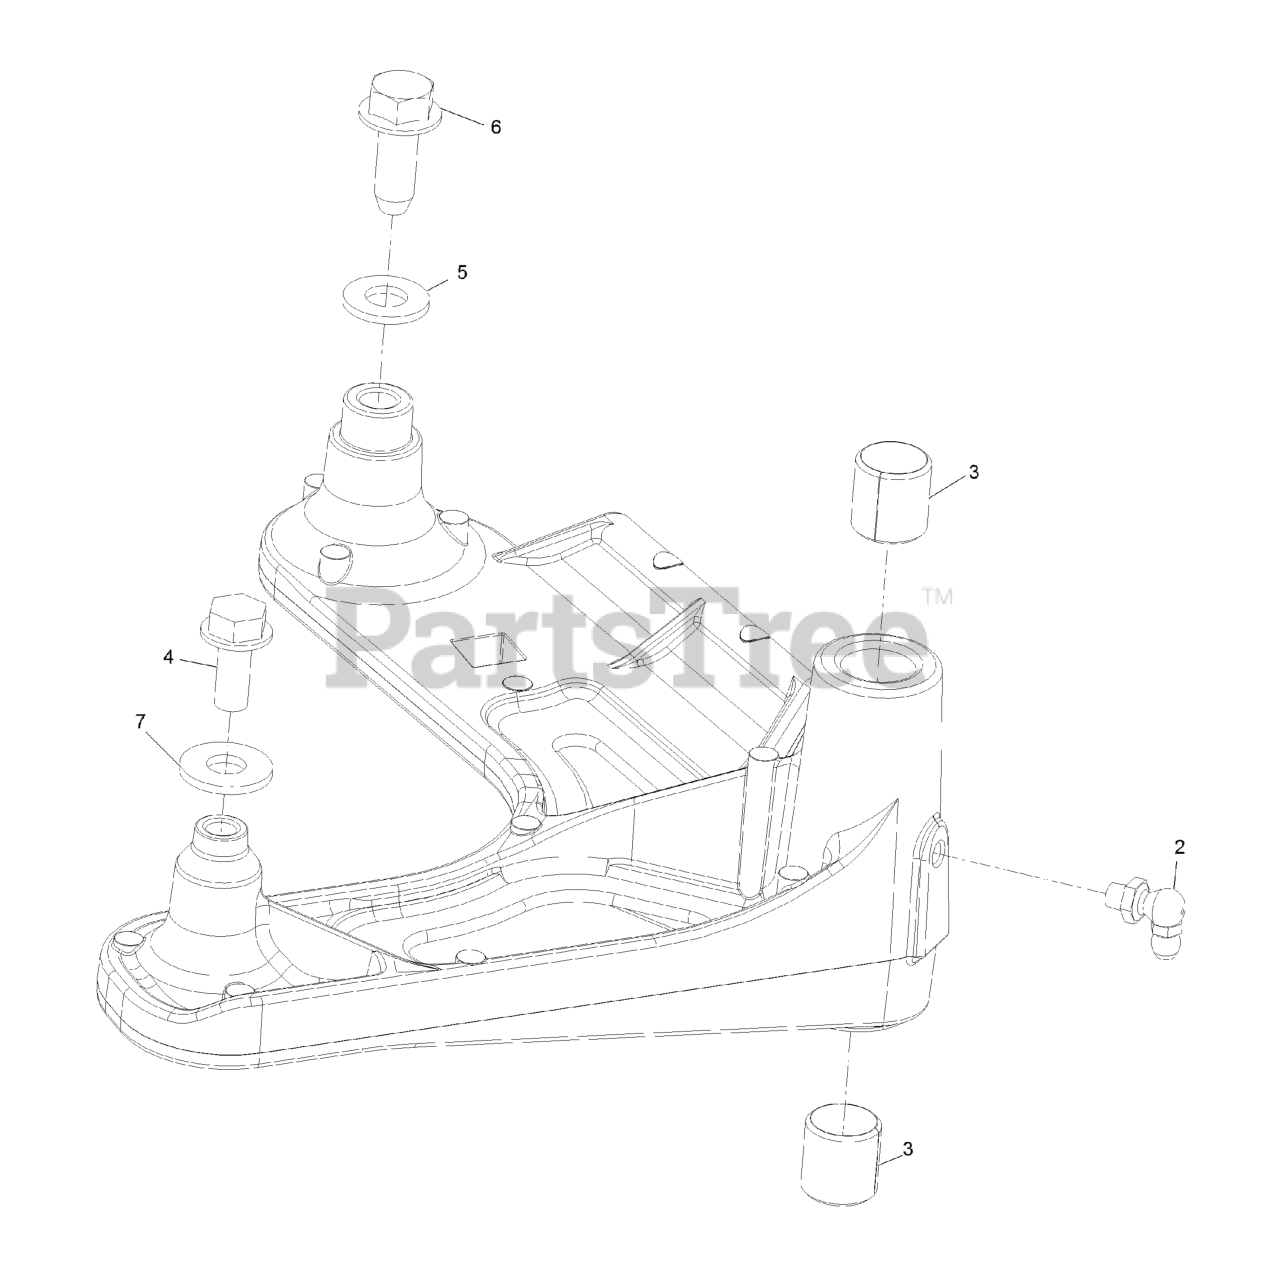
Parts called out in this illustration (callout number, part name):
2	FITTING-GREASE, 90 DEG
3	SLEEVE-BEARING
4	SCREW-THD ROLL, HWH
5	WASHER-FLAT
6	SCREW-FORMING, THREAD
7	WASHER-FLAT
